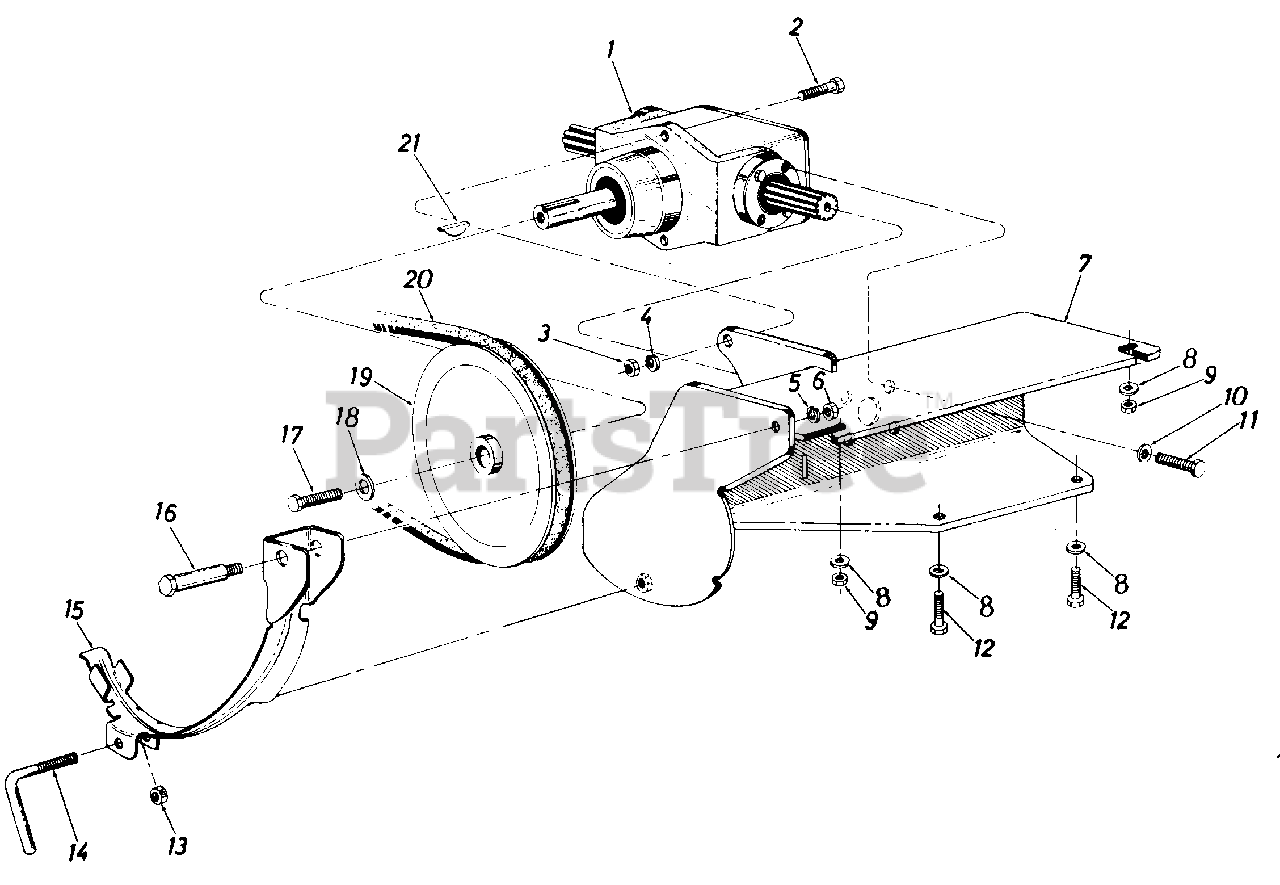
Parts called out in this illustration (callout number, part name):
1	"T" Drive Right Angle Ass'y.
2	Hex Scr. 3/8-16 x 1.00" Lg. (Grade 5)
3	Hex Nut 3/8-16 Thd.
4	L-Wash. 3/8" Scr.
5	L-Wash. 3/8" Scr.
6	Hex Nut 3/8-24 Thd.*
7	PTO Support Brkt. Ass'y.
8	Bell-Wash.
9	Hex Nut 3/8-16 Thd.*
10	Internal L-Wash. 1/4" I.D.
11	Hex Scr. 1/4-20 x 1.125" Lg.
12	Hex Scr. 3/8-16 x 1.00" Lg. (Grade 5)
13	Hex Cent. L-Nut 5/16-24 Thd.
14	PTO Locking Pin
15	PTO Belt Guard
16	Shld. Bolt .50" Dia. x 1.34" Lg.
17	Hex Scr. 5/16-18 x .75" Lg. (Grade 5)
18	Bell-Wash. 5/16" I.D.
19	PTO Pulley 7.00" O.D.
20	"V"-Belt .50" x 52" Lg.
21	#9 Hi-Pro Key 3/16 x 3/4"
